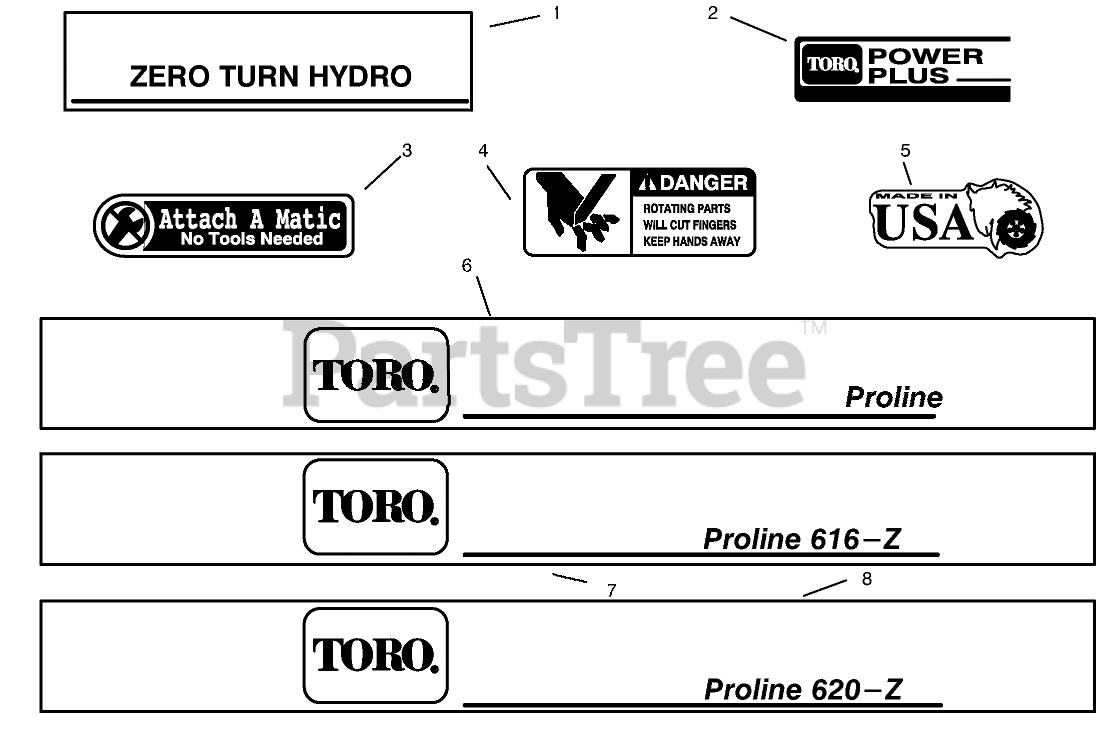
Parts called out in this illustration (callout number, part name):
1	DECAL-ZERO TURN HYD
2	DECAL POWER PLUS 16
3	Decal-Attac-O-Matic
4	DECAL - DANGER
5	Decal-Made in U.S.A.
6	DECAL-TORO REAR
7	DECAL - TORO 616-Z
8	DECAL - TORO 620-Z
